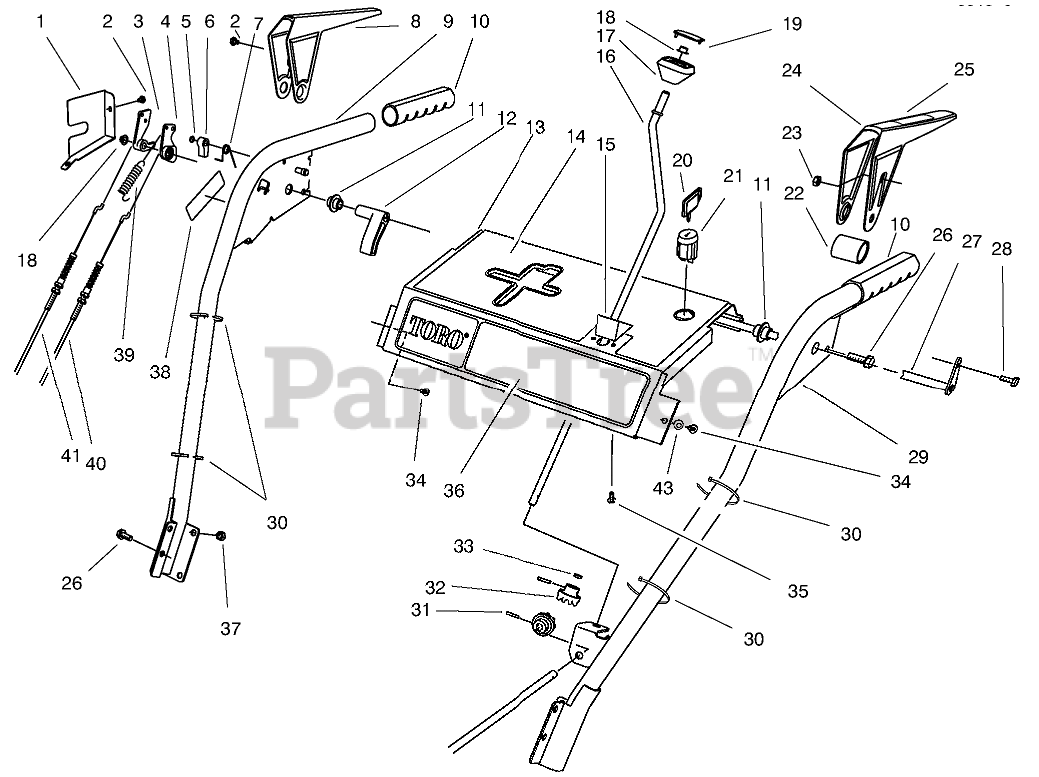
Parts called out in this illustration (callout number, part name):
1	Cover Lever Lock
2	SCREW-HH
3	TANG-LOCKING
4	CAM-RELEASE
5	E-RING-RETAINER
6	LATCH-LOCKING
7	SPRING-TORSION
8	Lever-Impeller
9	Handle-R.H.
10	GRIP-HANDLE
11	BUSHING-LEVER
12	LEVER-TRIP
13	Panel-Control
14	DECAL-TOP PANEL
15	PLATE-GUIDE
16	CRANK-ROD, CHUTE
17	KNOB-CONTROL, CHUTE
18	RETAINER-PUSH ON
19	COVER-KNOB
20	KEY-IGNITION
21	SWITCH
22	SPACER-LEVER, TRACTION
23	NUT-LOCK, NI
24	Lever-Traction
25	DECAL-LEVER
26	SCREW-HHF
27	CROSS ROD ASM
28	SCREW-HWH
29	Handle-L.H.
30	TIE-CABLE
31	PIN-SPRING
32	GEAR-UNIVERSAL
33	WASHER-RUBBER
34	SCREW-HWHTF
35	SCREW
36	DECAL - FRONT PANEL
37	NUT-LOCK, NI
38	DECAL-WARNING
39	SPRING-EXTENSION
40	CABLE-TRACTION
41	CABLE-IMPELLER
43	WASHER-FLAT
